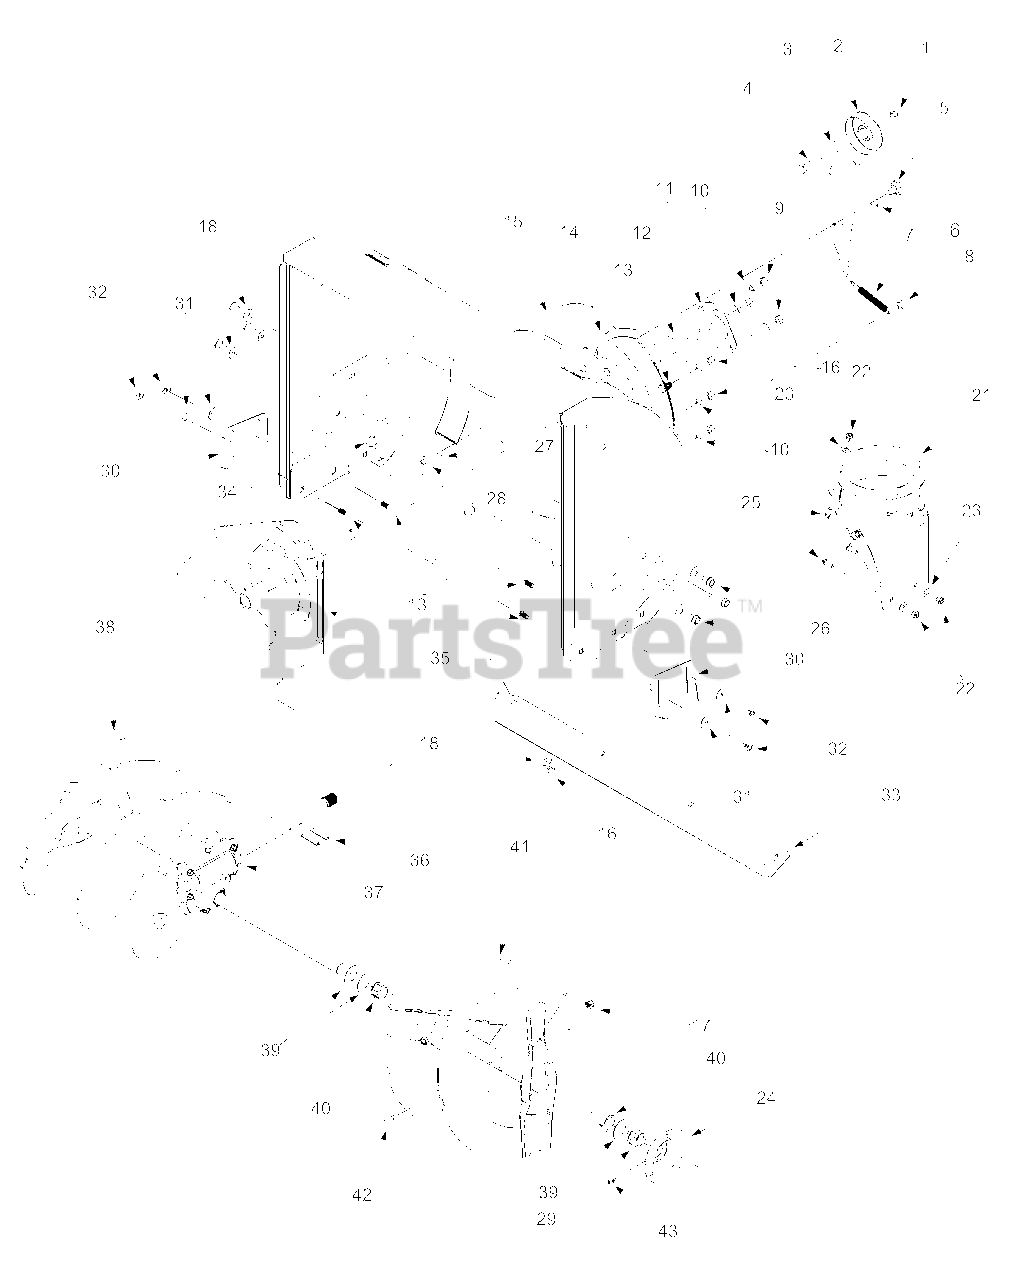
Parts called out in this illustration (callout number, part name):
1	Lock Jam Nut 3/8-24
2	Flat Idler
4	Hex Cap Screw 3/8-24 x 1.50
5	Shoulder Screw
6	Wave Washer
7	Extension Spring
8	Hex Nut 5/16-18
9	Hex Nut 5/16-18
10	Lock Washer 5/16
11	Housing
12	Ball Bearing
13	Carriage Bolt 5/16-18 x .75
17	Lock Nut 5/16-18
18	Bell Washer
21	Chute Adapter
22	Hex Lock Nut 1/4-20
23	Flat Washer
24	Bearing Housing w/Fitting
25	Carriage Screw 1/4-20 x .75
26	Hex Washer Screw 5/16-18
27	Lock Washer 3/8
28	Hex Nut 3/8-16
29	Hex Flange Bearing
31	Bell Washer
32	Hex Nut 5/16-18
34	Carriage Bolt 5/16-18 x .62
37	28" Gear Assembly
39	Flat Washer
40	Flange Bushing
42	Shear Bolt 5/16-18 x 1.5
43	Grease Fitting
